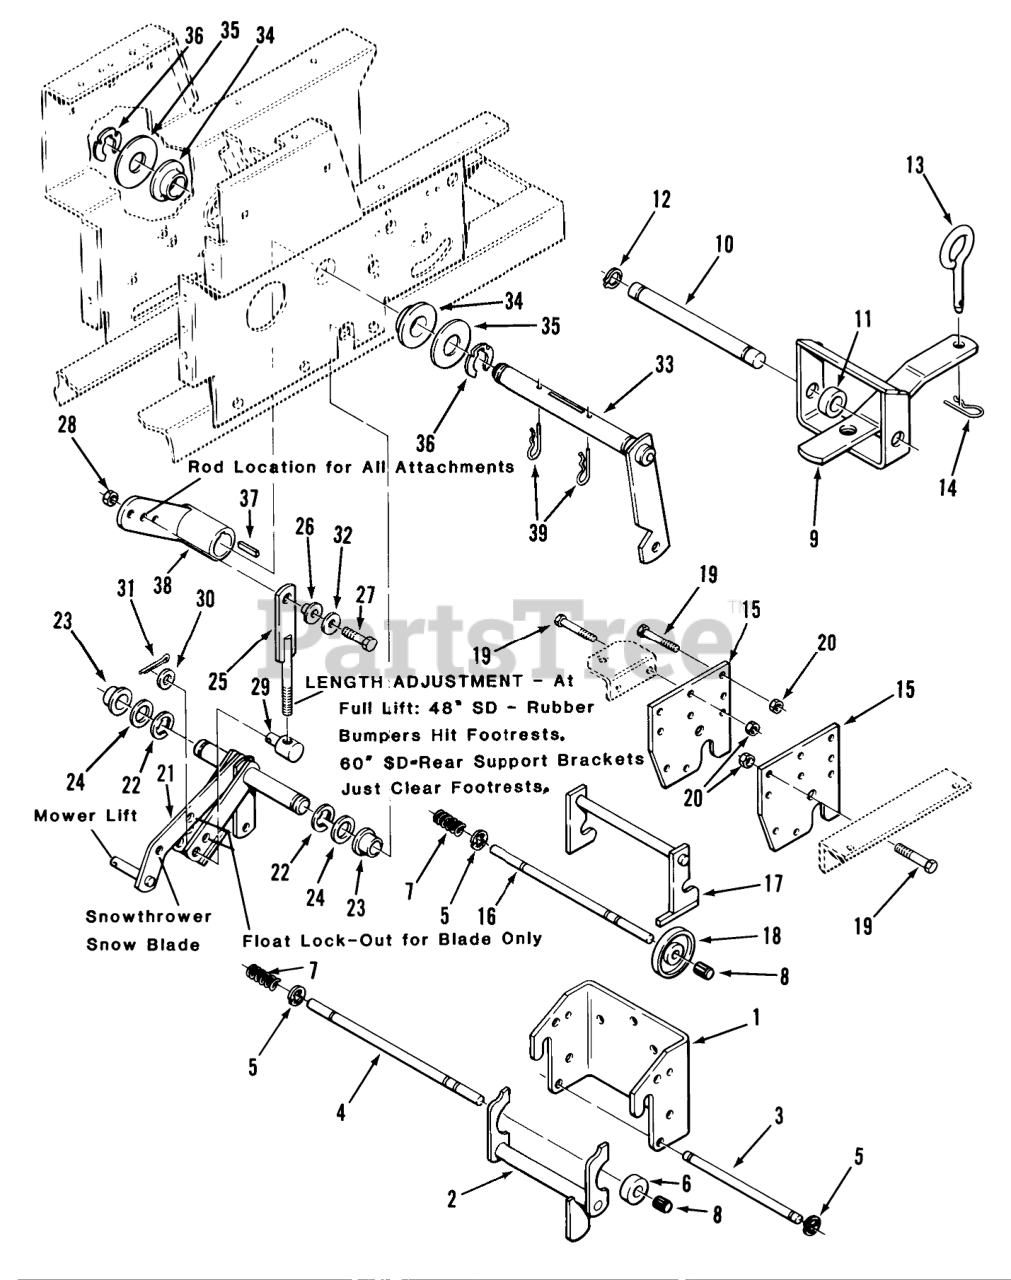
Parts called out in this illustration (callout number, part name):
1	HITCH-FRONT
2	Assy-Latch
3	ROD-LATCH PIVOT
4	ROD-LOCK
5	RING-RETAINING
7	SPRING
8	CAP-ROD, PLUNGER
9	Drawbar Hitch
10	Shaft-Drawbar Hitch
11	SPACER-OUTER
12	E-RING
13	PIN-TOOL
14	Hairpin Cotter
15	PLATE - HITCH R
17	ASSY LATCH HITCH R
19	Bolt 3/8-16 x 1
21	Lift Bar and Bellcrank
22	E Ring
23	BEARING
24	WASHER
25	Lift Rod
26	SPACER-BUSHING
27	BOLT
28	NUT
29	Trunnion-Threaded
30	Washer
31	Pop Rivet
32	WASHER
33	Lift lever
34	BEARING-FLANGE
35	WASHER
36	Retainer
37	KEY-SQUARE
38	Bellcrank
39	Pin-Cotter
